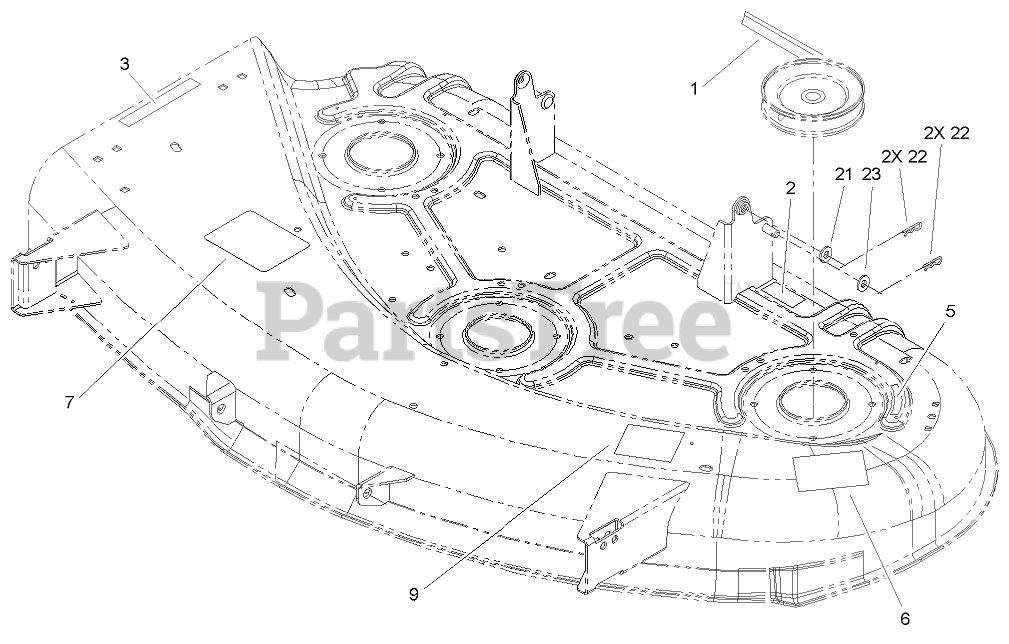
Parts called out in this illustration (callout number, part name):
1	V-BELT, 44IN DECK
2	DECAL-WARNING
3	DECAL-DANGER
5	DECAL-DANGER, SHIELD
6	DECAL-DANGER
7	DECAL-INSTALL, BELT
9	DECAL-ADJUSTMENT, WHEEL
21	WASHER-FLAT
22	PIN-COTTER
23	WASHER-HARDENED
